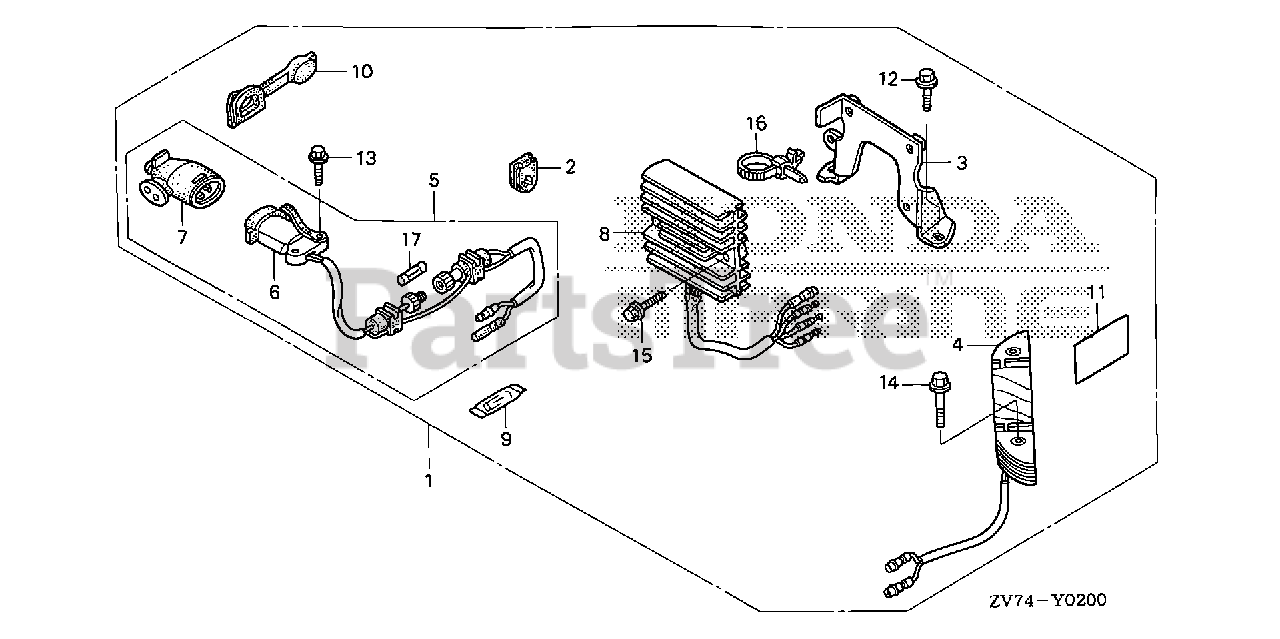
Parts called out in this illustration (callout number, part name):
1	RECEPTACLE KIT, CHARGE (6A)
2	GROMMET, WIRE
3	BRACKET, REGULATOR
4	COIL ASSY., CHARGE (12V-6A)
5	RECEPTACLE ASSY., CHARGE
6	RECEPTACLE
7	PLUG, RECEPTACLE
8	RECTIFIER ASSY., REGULATOR
9	FUSE, SPARE (15A)
10	GROMMET, CASE (LOWER) (C)
11	MARK, RECEPTACLE (6A)
12	BOLT, FLANGE (6X12) (CT200)
13	BOLT, FLANGE (5X22)
14	BOLT, FLANGE (6X35) (CT200)
15	BOLT, FLANGE (6X20)
16	STRAP, CABLE (118MM) (BLACK)
17	FUSE (15A)
